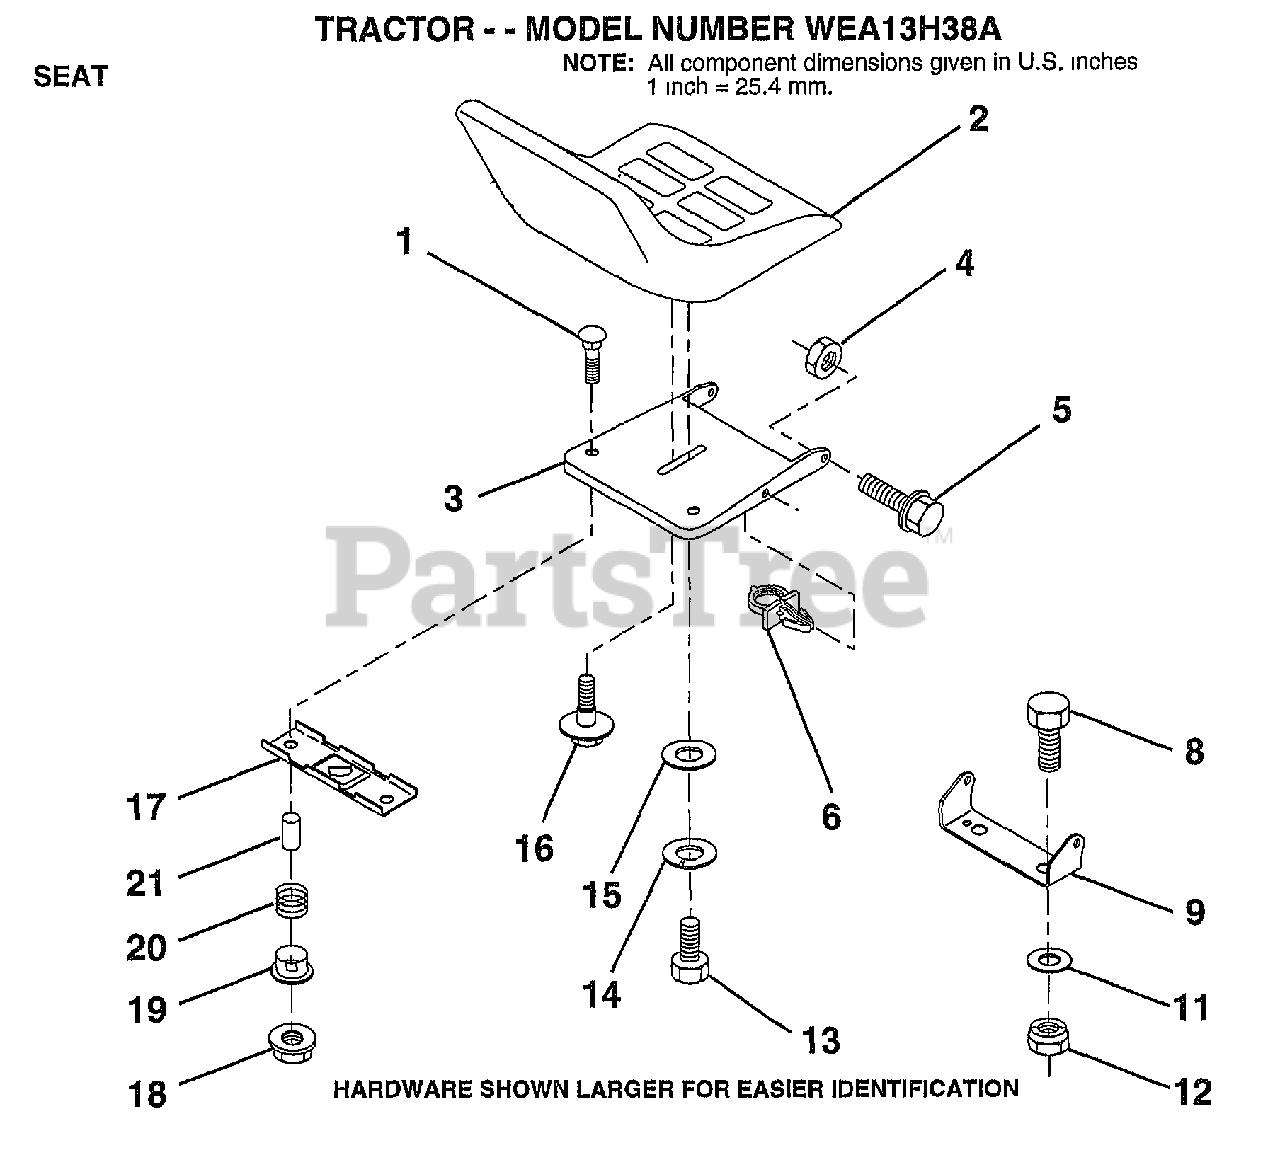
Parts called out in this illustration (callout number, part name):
1	BOLT-RD HD SQ NK
3	PAN-SEAT
4	NUT
5	"BOLT,SHOULDER"
6	CLIP.PUSH-IN.HING
8	BOLT
9	BRACKET PVT SEAT
11	WASHER
12	NUT
13	BOLT
14	LOCKWASHER
15	WASHER
16	"BOLT,SHOULDER"
17	BRKT SWITCH
19	BUSHING
20	SPRING
21	SPLIT SPACER
